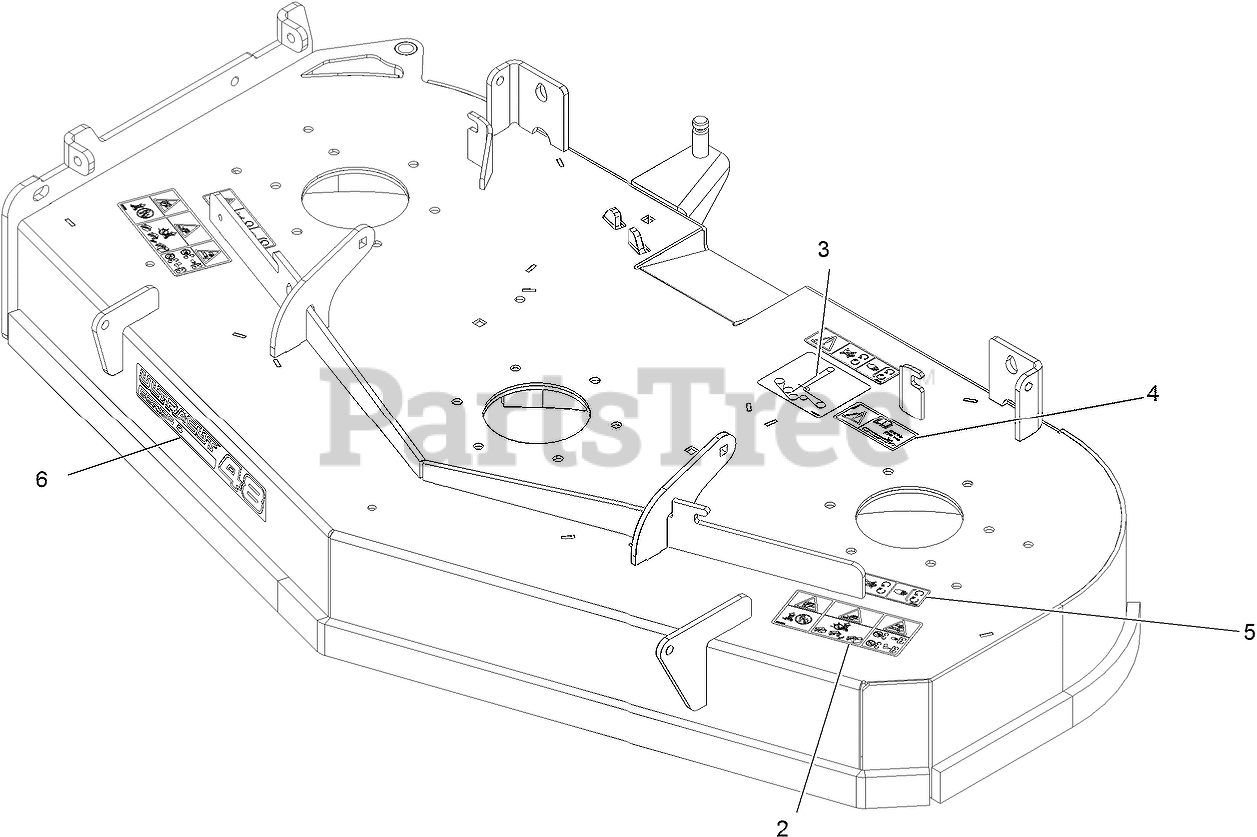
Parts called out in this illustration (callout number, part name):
2	DECAL-WARNING THROWN OBJ
3	DECAL-BELT ROUTING
4	DECAL-BOLT TORQUE
5	DECAL-COVER, MISSING
6	Decal, 484
